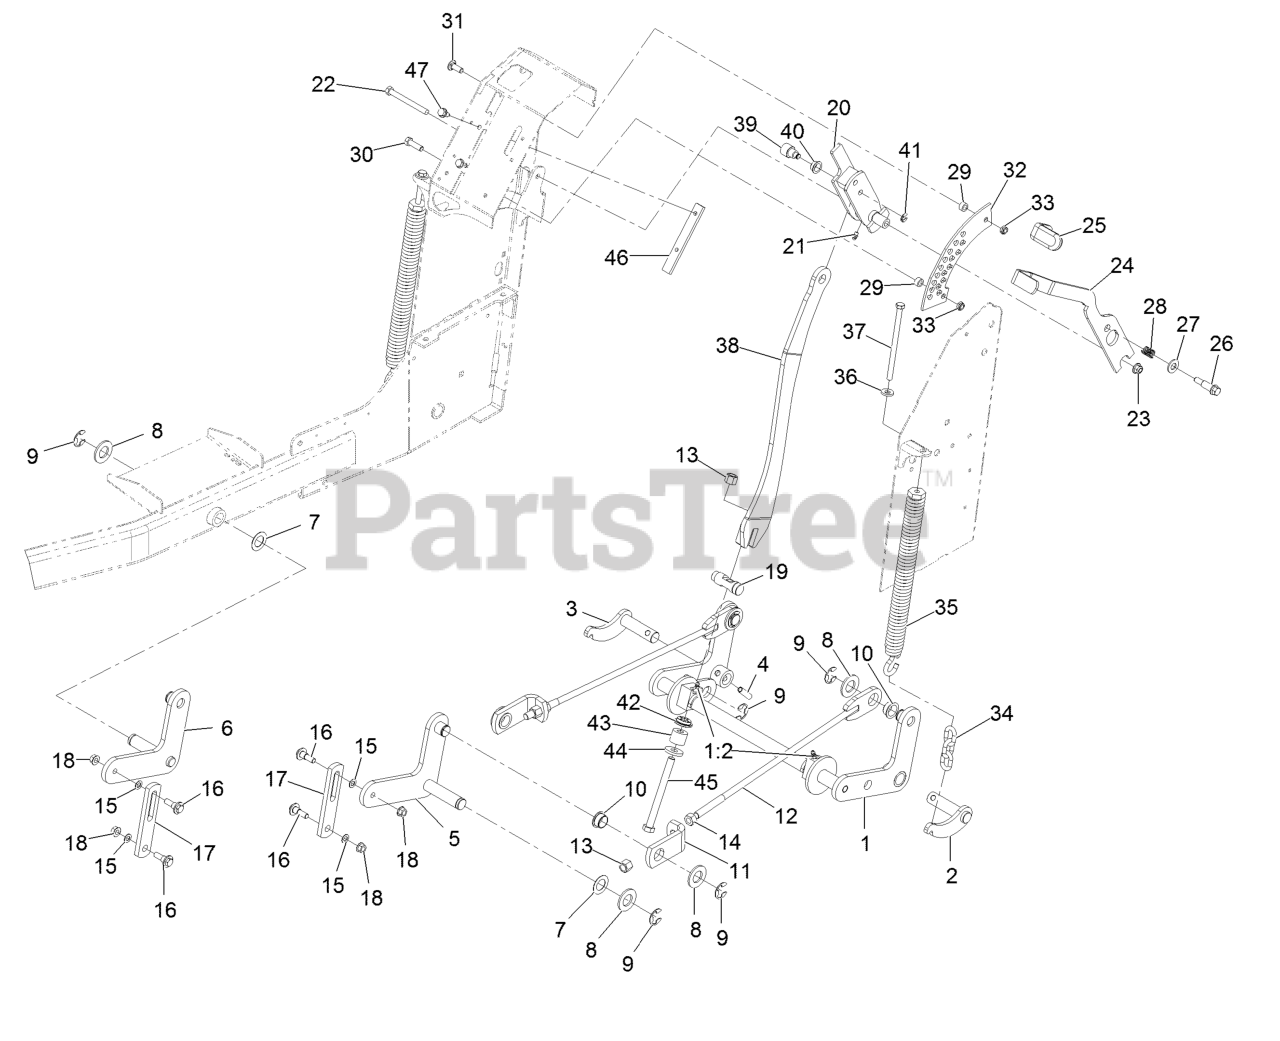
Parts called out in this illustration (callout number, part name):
1	Rear Crossshaft ASM
1:2	Zerk-45deg 1/4-28
2	Shaft-Pivot, LH
3	Shaft-Pivot, RH
4	Pin-Spiral
5	Arm-Lift, LH
6	Arm-Lift, RH
7	Washer-Thrust
8	Washer-7/8 SAE
10	Bearing-Flange
11	Bracket-Lift Rod
12	Lift Rod ASM
13	Nut-Nyloc 1/2-13
14	Nut-Hex 1/2-13
16	Screw-Hex Flange 3/8-16 X .80
17	Link-Lift
18	Nut-3/8-16 Flanged Side Lock
19	Pin-HOC
20	HOC Handle ASM
21	Zerk 1/4-28 Str Thrd Forming
22	Screw-HH 3/8-16 X 3 3/4
23	Nut-Nyloc 3/8-16 Flg
24	Lever-HOC
25	Grip-Lever
26	Screw-Shoulder
27	Washer-1/2 SAE
29	Bushing
30	Screw-HH 3/8-16 X 1 1/4
31	Bolt-Carriage 3/8-16 X 1
32	Bracket-HOC
33	Nut-Nyloc 3/8-16 Thin
34	Chain-Decklift
35	Spring-Extension
36	Washer-Spring Disc 3/8
37	Bolt-HH 3/8-16 X 6 Tap
38	Bar-Lift
39	Hub-Pivot
40	Bearing-Flange
41	Ring-Retaining
42	Seat-Spring
43	Spring-Urethane
45	Screw-HH 1/2-13 X 5 1/2
46	Skid-Handle, Lift
47	Screw-HWH 5/16-18 X 3/4 Tf
